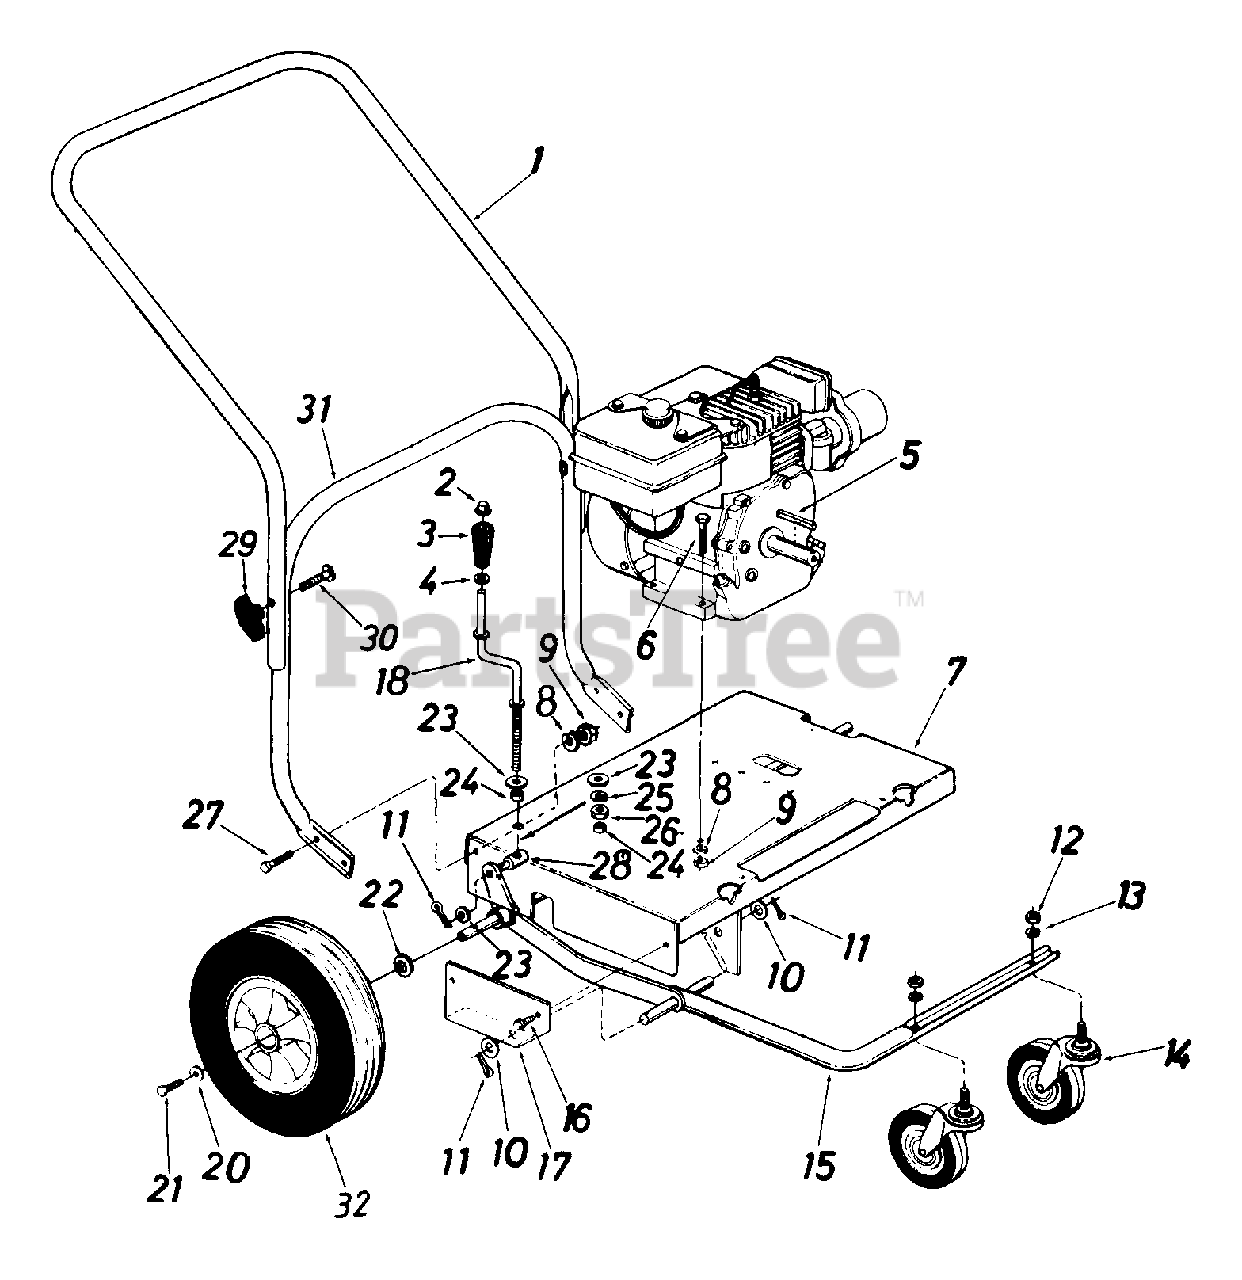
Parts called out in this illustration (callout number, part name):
2	Push Nut 3/8" Rod
3	Crank Knob
4	Fl-Wash. .385" I.D. x.62"
5	Sq. Key 1/4" x 2.0" Lg.
6	Hex Bolt 5/16-18 x 1.50" Lg.
9	Hex Nut 5/16-18 Thd.
10	Fl-Wash. .63" I.D. x 1.25"
11	Cotter Pin 1/8" Dia. x 1.0"
12	Hex Nut 1/2-13 Thd.
13	L-Wash. 1/2" I.D.
14	Swivel Caster Wheel 5" Dia. x 1.25"
20	Fl-Wash. .34" I.D. x .87" O.D.
21	Hex Locking Bolt 5/16-24 x .64" Lg.
22	Fl-Wash.
23	Fl-Wash. .38" I.D. x .57"
24	Spacer .382" I.D. x .50" x .180" Lg.
25	L-Wash. 3/8" I.D.
26	Hex Nut 3/8-8 Thd.
27	Hex Bolt 5/16-18 x .75" Lg.
28	Ferrule
29	Hand Knob
30	Carriage Bolt 5/16-18 x 2.0"
32	Wheel Ass'y. Comp. 12" x 3" (Plastic)
